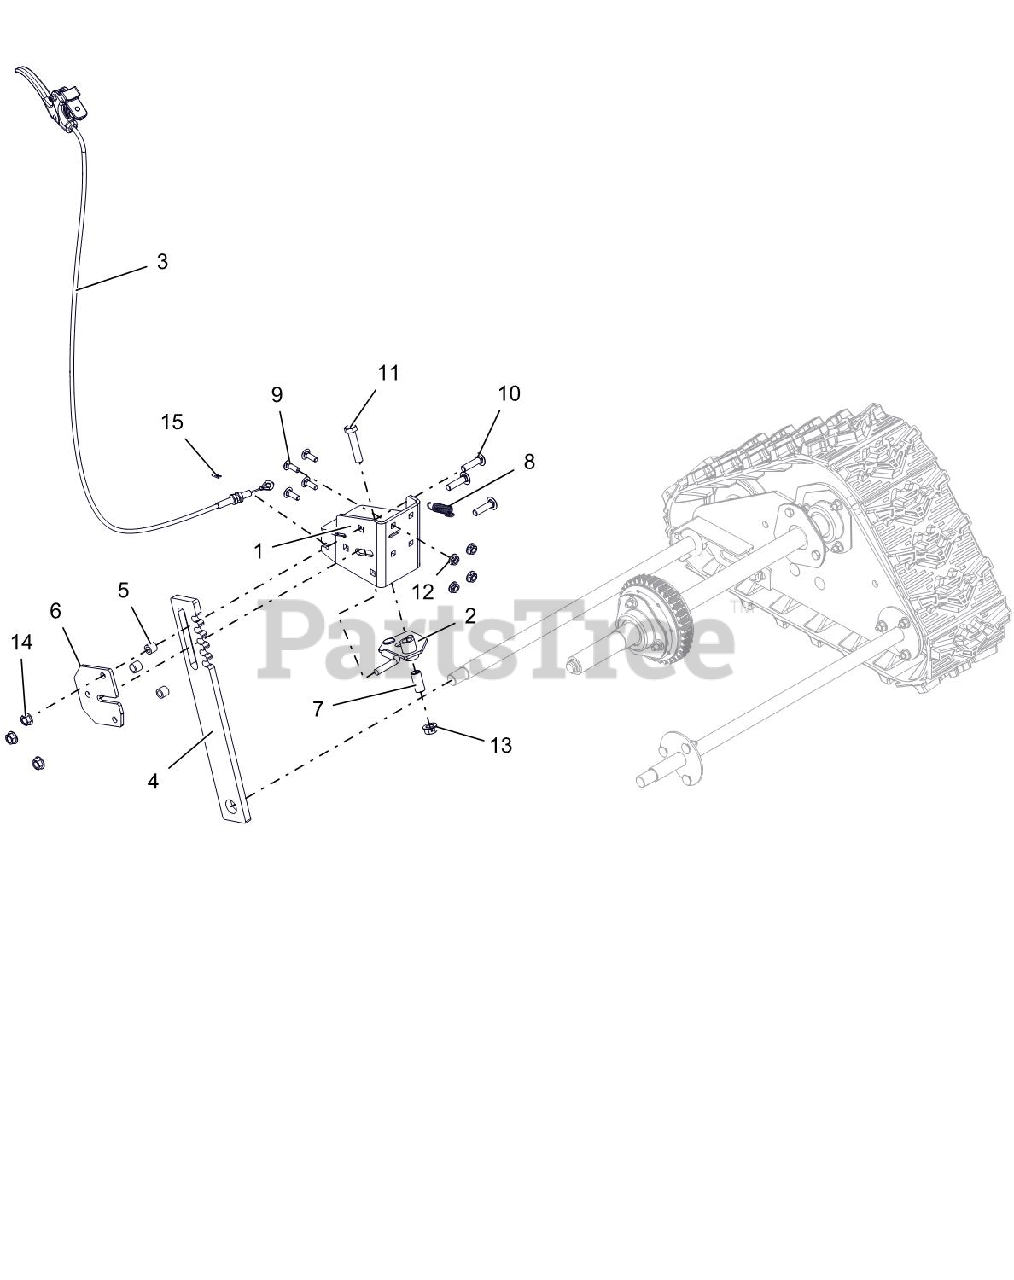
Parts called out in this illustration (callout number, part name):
1	BRACKET,HEIGHT ADJUSTER-PRO
2	LOCK,HEIGHT ADJUSTER TRIGGER
3	CABLE, TRACK REMOTE
4	STOP, HEIGHT ADJUSTER-PRO
5	SPACER .50 X .32 X .42
6	PLATE, HEIGHT ADJUSTER
7	BSHG-SLV .385X.500X1.045
8	SPRING-EXT .047 X .438 X 1.85
9	@BLT-RDHDSQNK .25-20X.75 G5YZ
10	@BLT-RHDSHSQNK.31-18X1.25 G5YZ
11	@BLT-HEX .38-16X1.75 GR5 YWZC
12	@NUT-LK-CTR-FLG .25-20 YWZC
13	NUT-LK-CTR-FLG .38-16 YWZC
14	@NUT-LK-TOP-FLG .31-18 YWZC
15	PIN-HAIR INT .06X.18X.77
